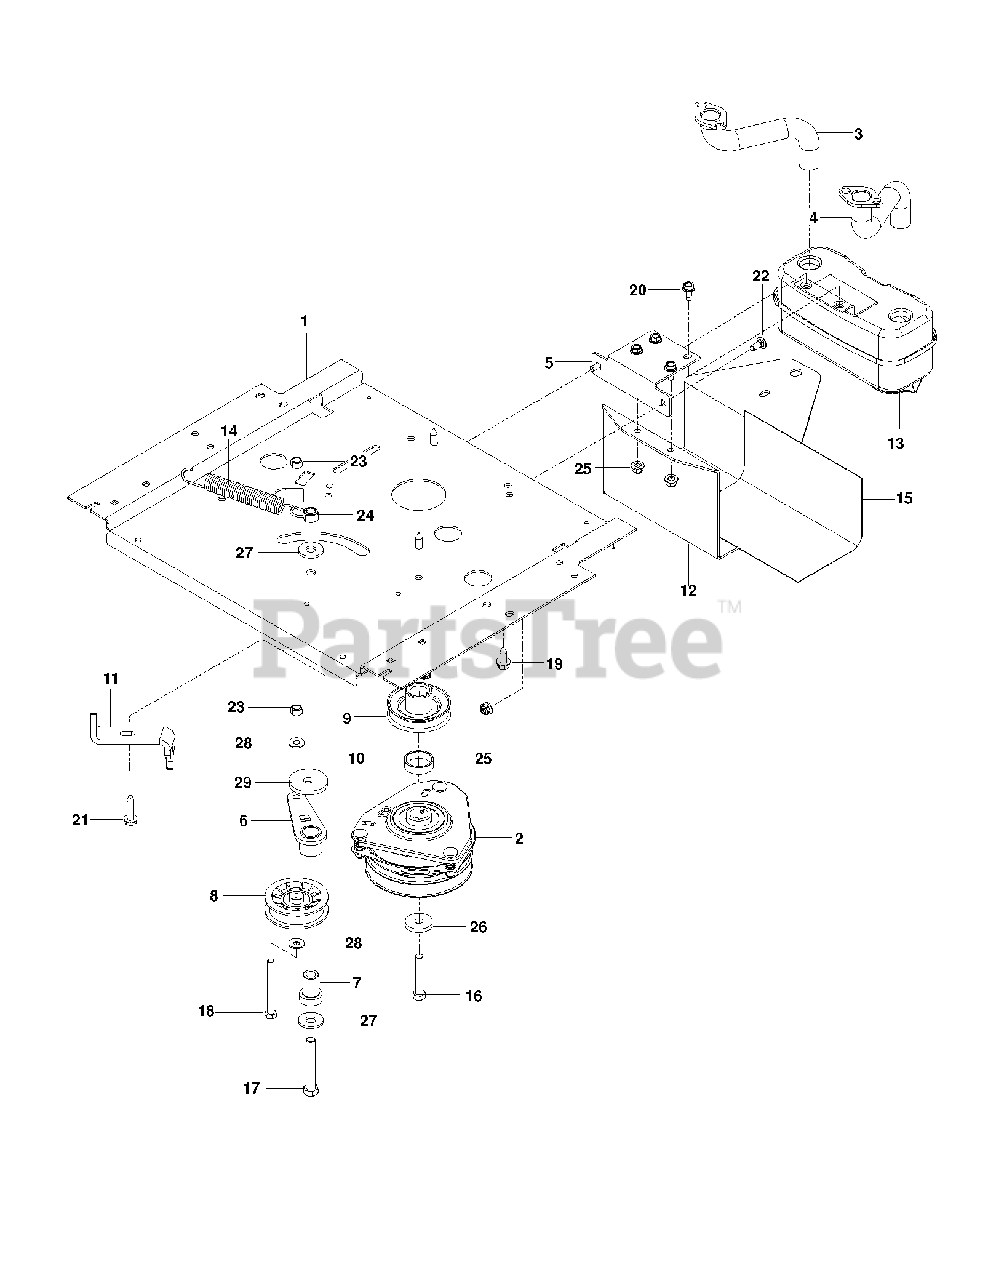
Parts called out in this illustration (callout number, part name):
1	PLATE, ENGINE WIDE, BLACK
2	CLUTCH.ELECTRIC.LT.48"*
3	RP.EXHAUST.TUBE.LH.BS/TWIN
4	EXHAUST.TUBE.RH.BS/TWIN
5	BRACKET, MUFFLER, BLACK
6	IDLER ARM WELDMENT
7	IDLER SPINDLE
8	PULLEY, IDLER RAKE & ZTR
9	RP PULLEY, ENGINE
10	SPACER, HUB PULLEY
11	CLUTCH STOP BLK
12	GUARD, MUFFLER, BLACK
13	MUFFLER ASM TWIN
14	SPRING, DECK DRIVE
15	HEAT SHIELD
16	HCS 7/16-20 X 2.5 GR8
17	HCS 1/2C X 3 1/4
18	HCS 3/8-16X3 1/2 GR5
19	HHFS 3/8-16 X 1.0 THD FORMING
20	BOLT 5/16-18 X 3/4
21	BOLT 3/8-16 X 1 1/2 ZINC CLEAR
22	BOLT 5/16C X 3/4" CARRIAGE
23	NUT 3/8-16 NYLOC
24	RP NUT 1/2-13 HEX NYLOC ZD
25	5/16-18 NYLOC FLANGE NUT
26	CLUTCH, WASHER
27	WASH USS FLAT 1/2
28	WASHER 5/16 FLAT
29	HEAVY WASHER
